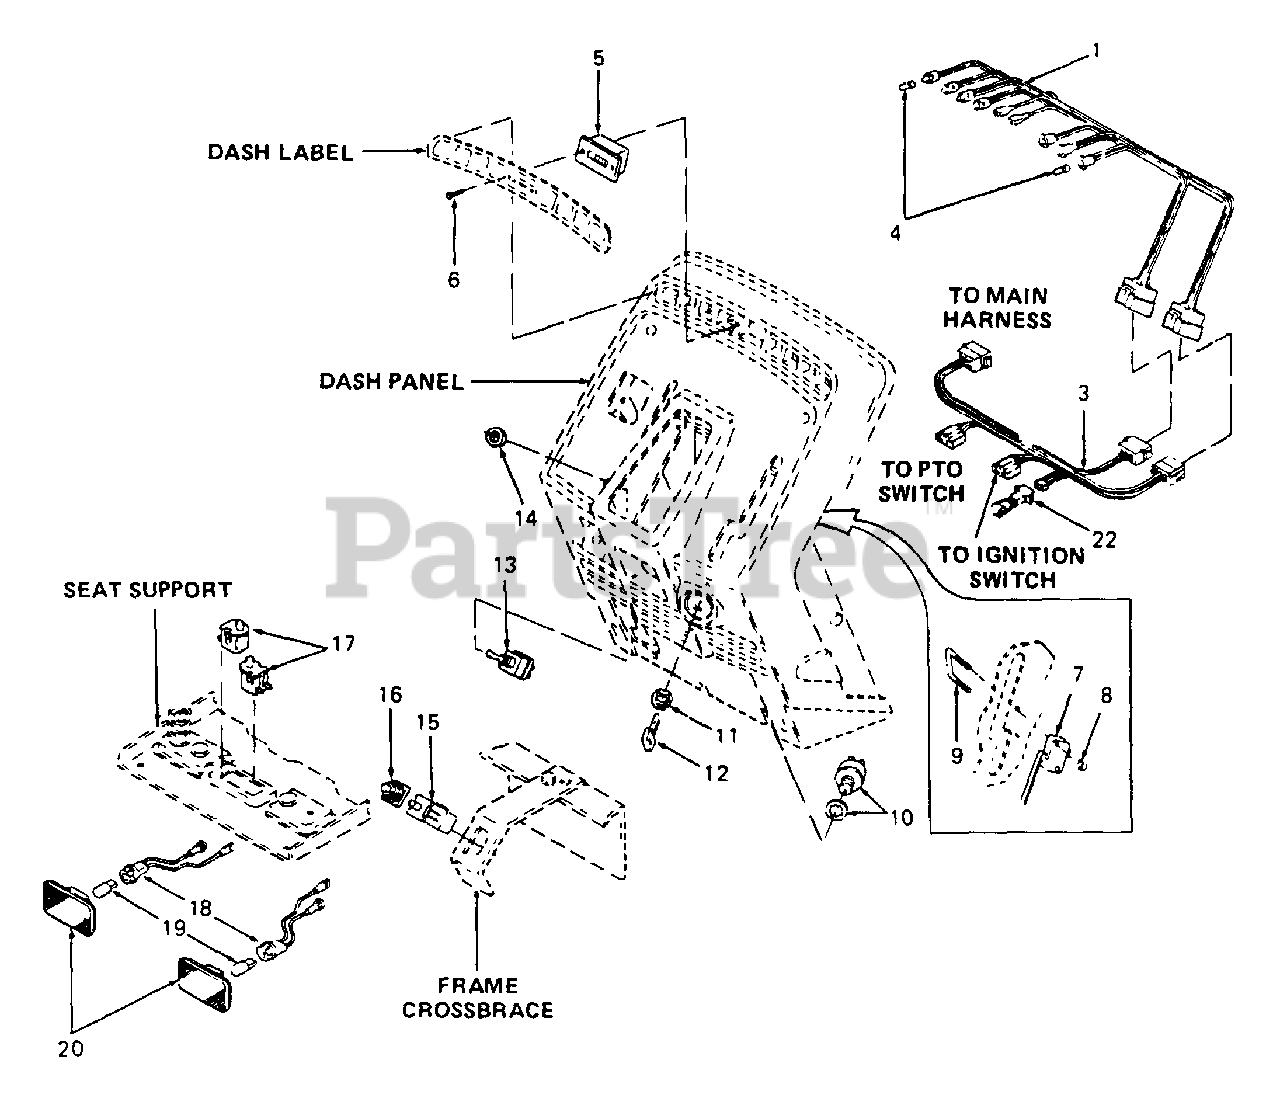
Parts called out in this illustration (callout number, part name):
1	Harness, Indicator Wire
3	Harness, Pedestal
4	Bulb, Indicator
5	Hour Meter
6	Screw, Truss Hd Tapp, #6 x .62 Lg
7	Switch, Reverse
8	Nut, Hex Insert Lock, #4-40
9	Screw, Switch
10	Switch, Ignition
11	Nut, Ignition Switch
12	Key, Ignition
13	Switch, PTO
14	Nut, Hex, 1/2-27 x .100 Thk
15	Switch, Interlock
16	Boot, Switch
17	Switch, Snap Mount
18	Cable Assy, Tail Light
19	Bulb, Tail Light
20	Lens Assy, Tail Light
22	Diode Assembly
